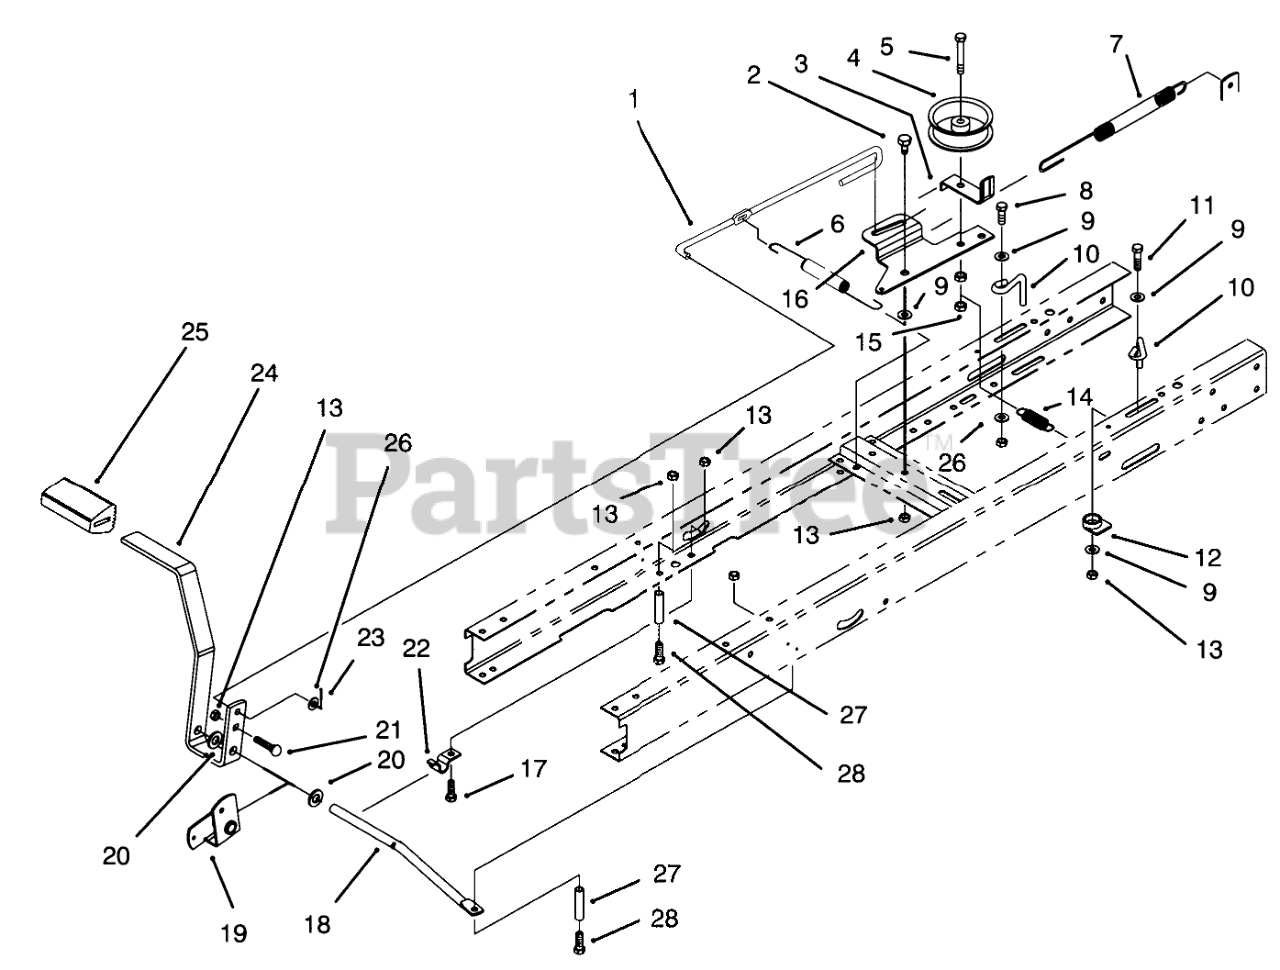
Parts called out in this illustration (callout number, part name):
1	ROD-CLUTCH/BRAKE
2	BOLT-SHOULDER
3	GUIDE-IDLER, BELT
4	Idler Pulley
5	SCREW-HH
6	SPRING-EXTENSION
7	BRAKE SPRING
8	SCREW-HH
9	WASHER-PIVOT
10	TRANS BELT GUIDE
11	SCREW-HH
12	GUIDE-CABLE
13	NUT-LOCK, NI
14	SPRING-EXTENSION
15	NUT-LOCK, NI
16	ARM-IDLER
17	SCREW-HH
18	ROD-PIVOT, PEDAL
19	BelIcrank
20	WASHER-FLAT
21	SCREW-CARR
22	CLAMP-PIVOT, SHIFT
23	PIN-COTTER
24	Pedal-Clutch/Brake
25	PAD-PEDAL
26	WASHER-PLAIN
27	TUBING-SPACER
28	SCREW-HH
